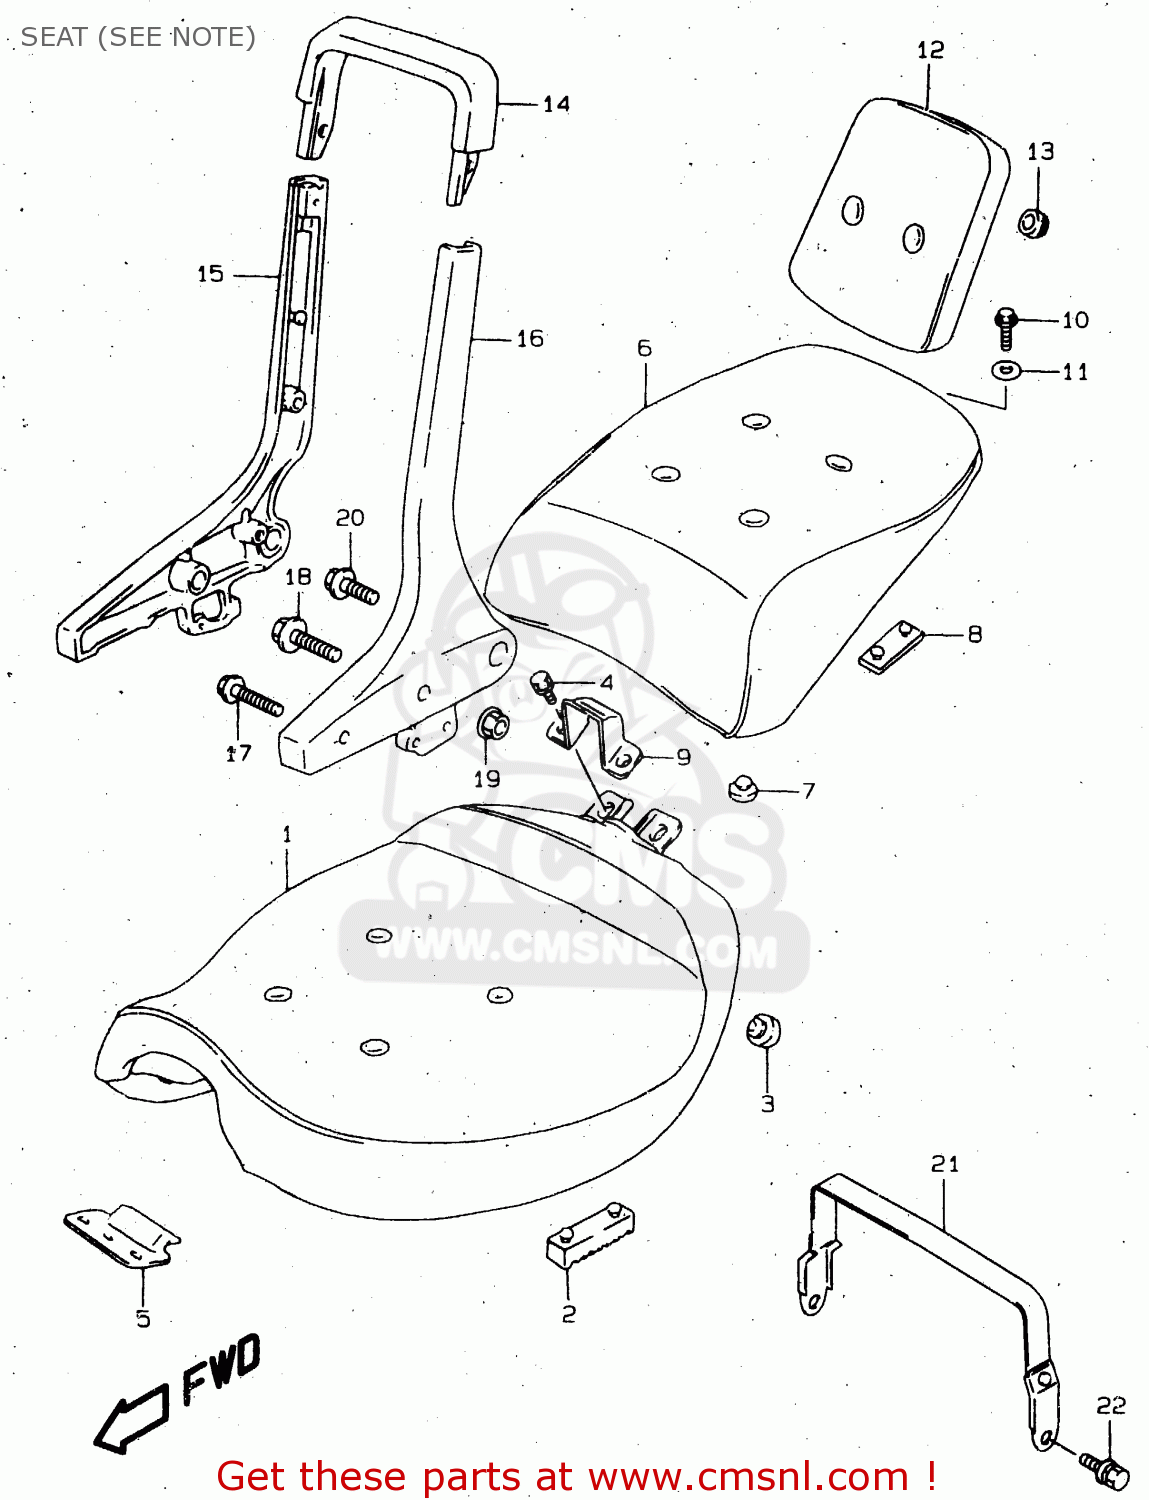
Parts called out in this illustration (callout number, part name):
1	SEAT ASSY
2	CUSHION,SEAT
3	CUSHION
4	BOLT
5	BRACKET,SEAT FR
6	SEAT ASSY,PILLION
7	CUSHION
8	CUSHION,PILLION SEAT RR
9	BRACKET,PILLION SEAT FR
10	BOLT(6X17.5)
11	WASHER(9.5X20X1)
12	PAD ASSY,SEAT
13	CUSHION
14	HANDLE,PILLION RIDER UPR
15	HANDLE,PILLION RIDER,RIGHT
16	HANDLE,PILLION RIDER,LEFT
17	BOLT, FRONT
18	BOLT
19	NUT
20	BOLT, REAR
21	BAND, SEAT
22	BOLT
